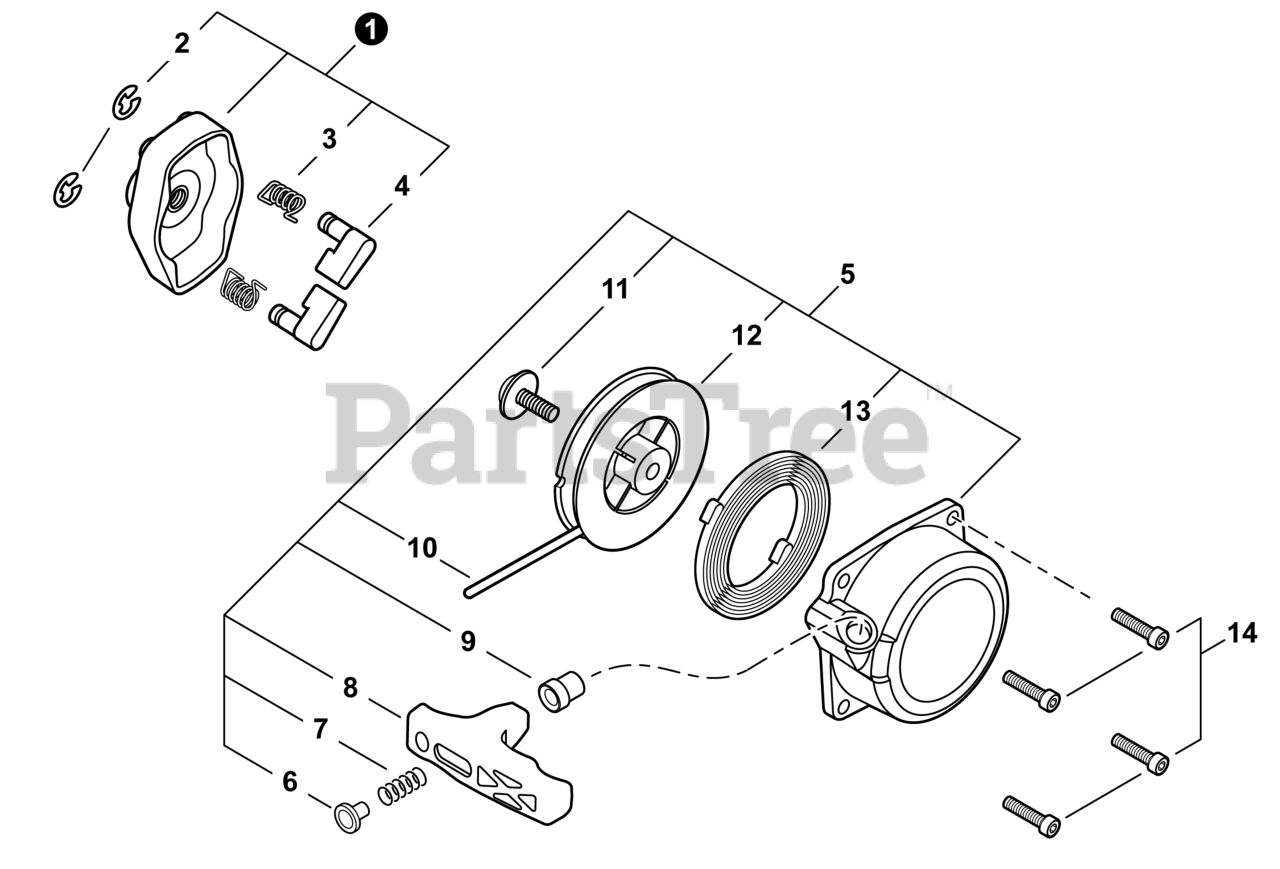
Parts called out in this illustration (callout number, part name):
1	PULLEY ASSY, STARTER
2	E-RING 4
3	SPRING, RETURN
4	PAWL, STARTER
5	STARTER ASSY, RECOIL
6	RETAINER, ROPE
7	SPRING, COMPRESSION
8	GRIP, STARTER
9	GUIDE, ROPE
12	REEL, ROPE
13	SPRING, SPIRAL
14	BOLT, TORX 5×20
